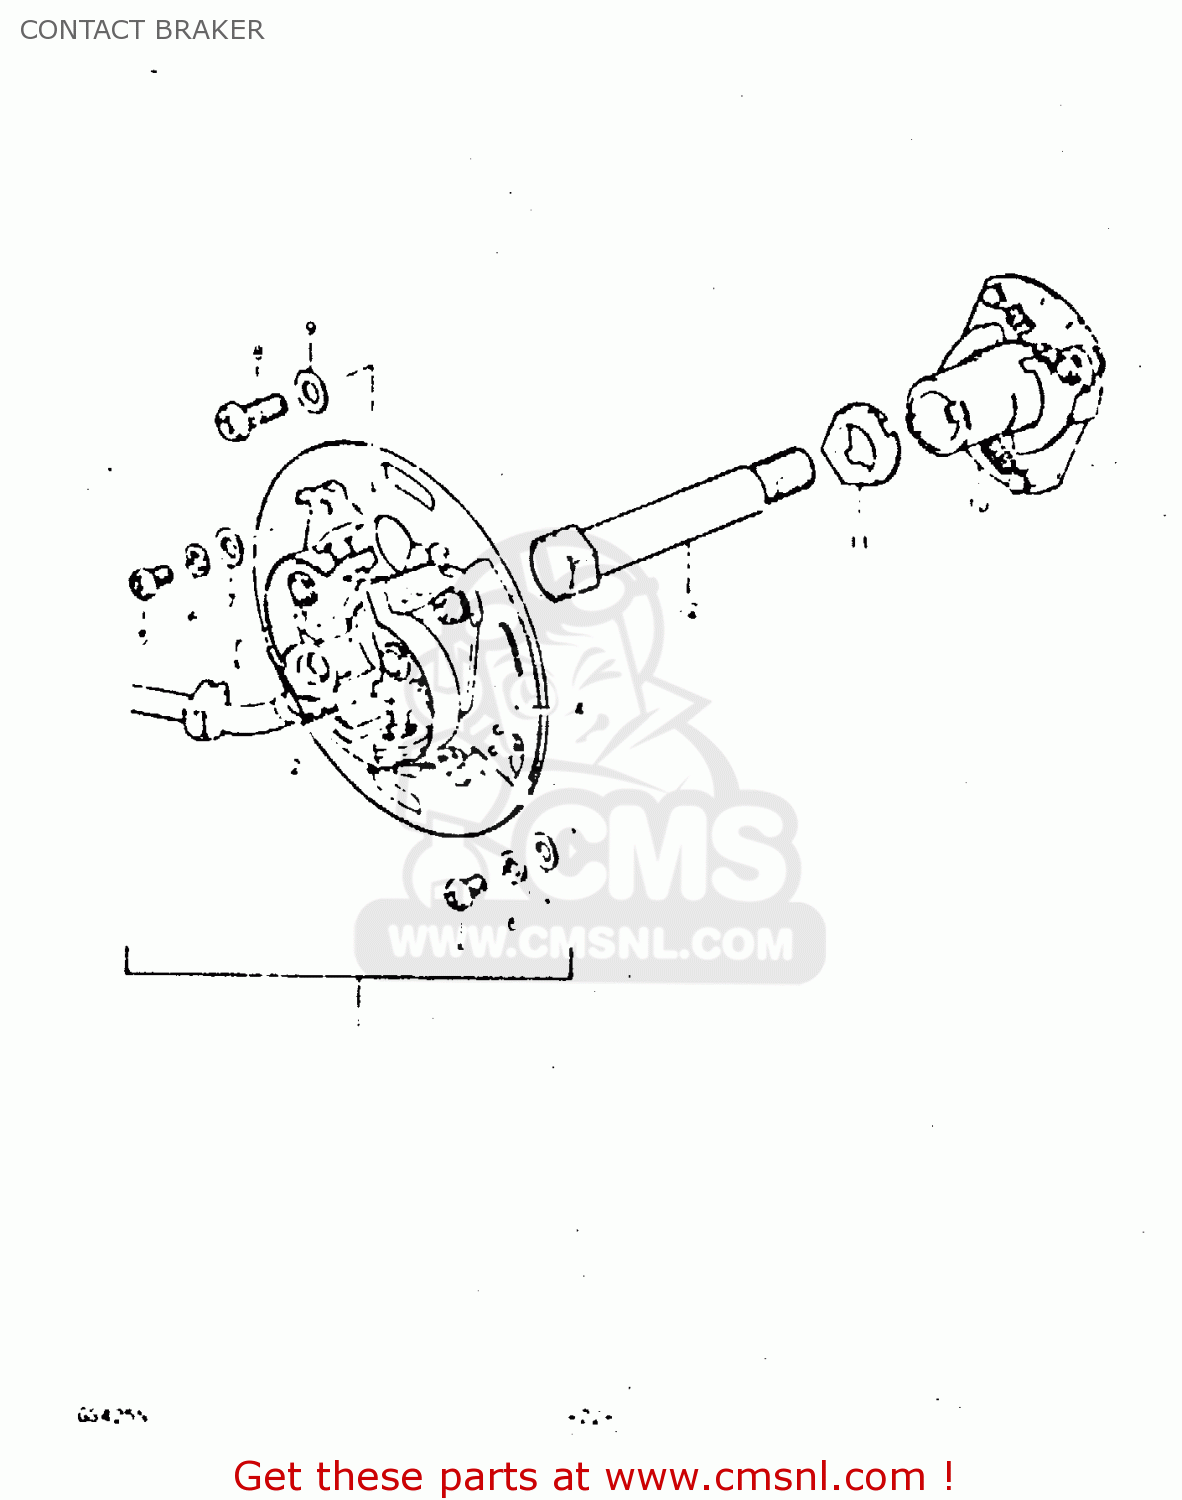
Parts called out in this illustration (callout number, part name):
1	SIGNAL GENERATOR ASSEMBLY
2	POINT ASSEMBLY,CONTACT
3	POINT ASSEMBLY,CONTACT
4	PLATE,CONTACT POINT
5	SCREW
6	LOCK WASHER
7	WASHER
8	SCREW(5X12)
9	WASHER 5MM
10	GOVERNOR ASSEMBLY
11	WASHER
12	BOLT
